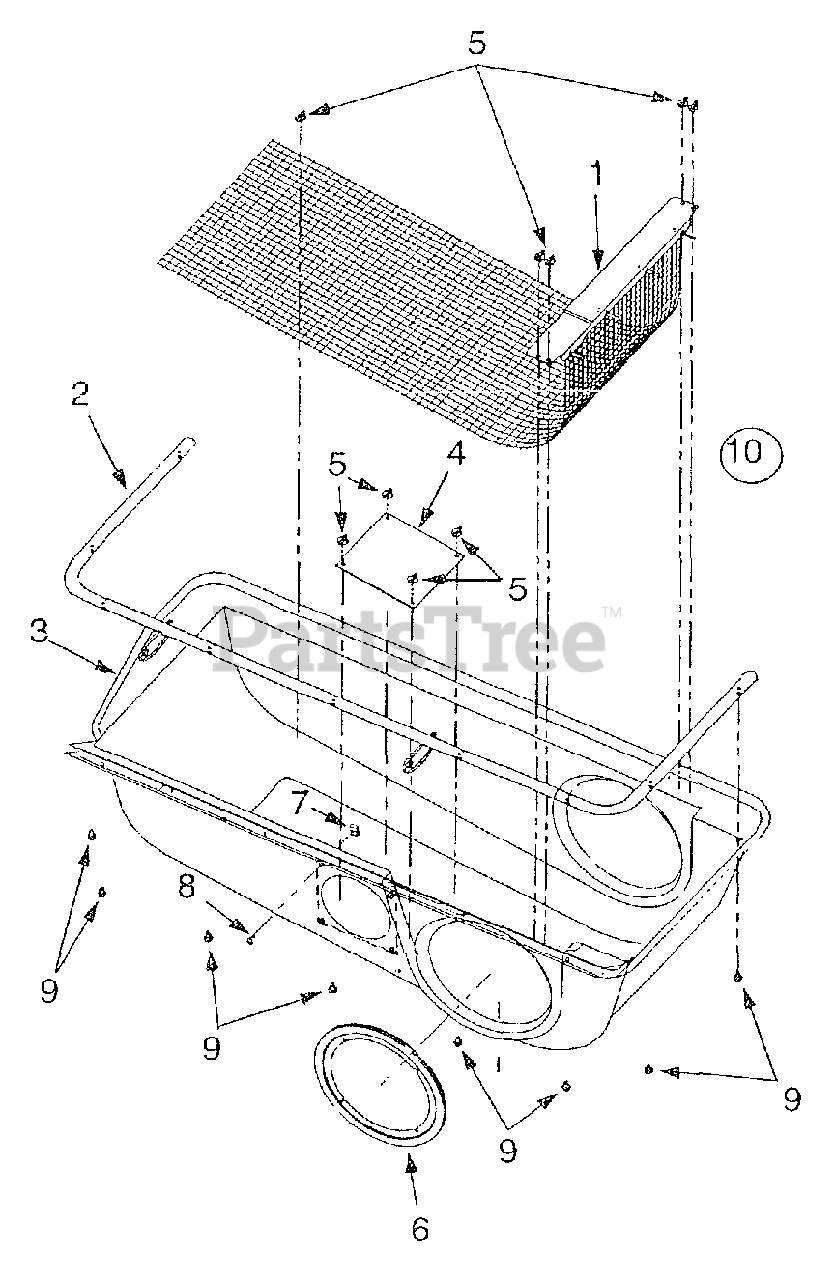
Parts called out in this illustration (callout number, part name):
3	Grass Catcher Cover
4	Plastic Plate
5	Zip Twist Fastener
6	Tube Seal
7	U-Type Speed Nut
8	Screw, #10-16 x 0.5"
9	Hex Screw, 1/4-20 x 0.5"
10	Grass Catcher Cover Assembly
